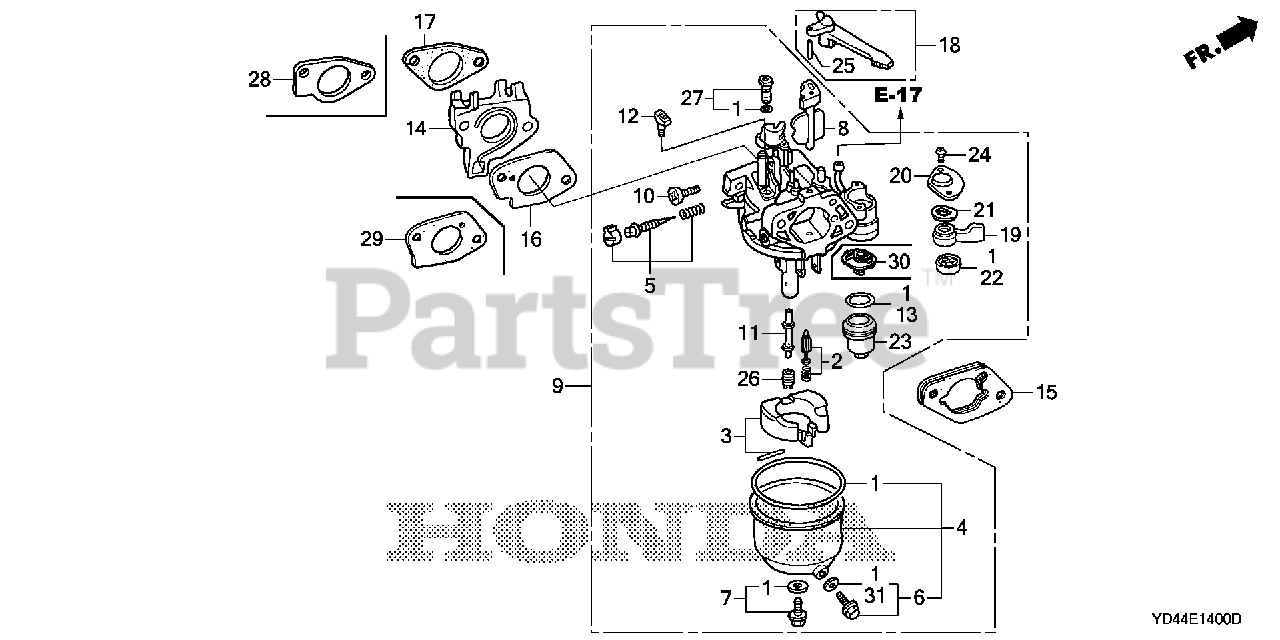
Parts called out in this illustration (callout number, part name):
1	GASKET SET (INCLUDES 16173-001-004)
2	VALVE SET, FLOAT
4	CHAMBER SET, FLOAT
5	SCREW SET, PILOT
6	SCREW SET, DRAIN
7	SCREW SET
9	CARBURETOR ASSY. (BE80B B)
10	SCREW, THROTTLE STOP
11	NOZZLE, MAIN
12	COLLAR, SETTING
13	GASKET, FUEL STRAINER CUP
14	INSULATOR, CARBURETOR
15	SPACER, CARBURETOR
16	GASKET, CARBURETOR
17	GASKET, INSULATOR
18	LEVER, CHOKE (STD)
19	LEVER, PETCOCK
20	PLATE, LEVER SETTING
21	SPRING, PETCOCK LEVER
22	GASKET, PETCOCK
23	CUP, FUEL STRAINER
24	SCREW, PAN (3X6)
25	PIN, SPRING (2X12)
26	JET, MAIN (#88)
26	JET, MAIN (#90)
26	JET, MAIN (#92)
27	JET SET, PILOT (#35)
